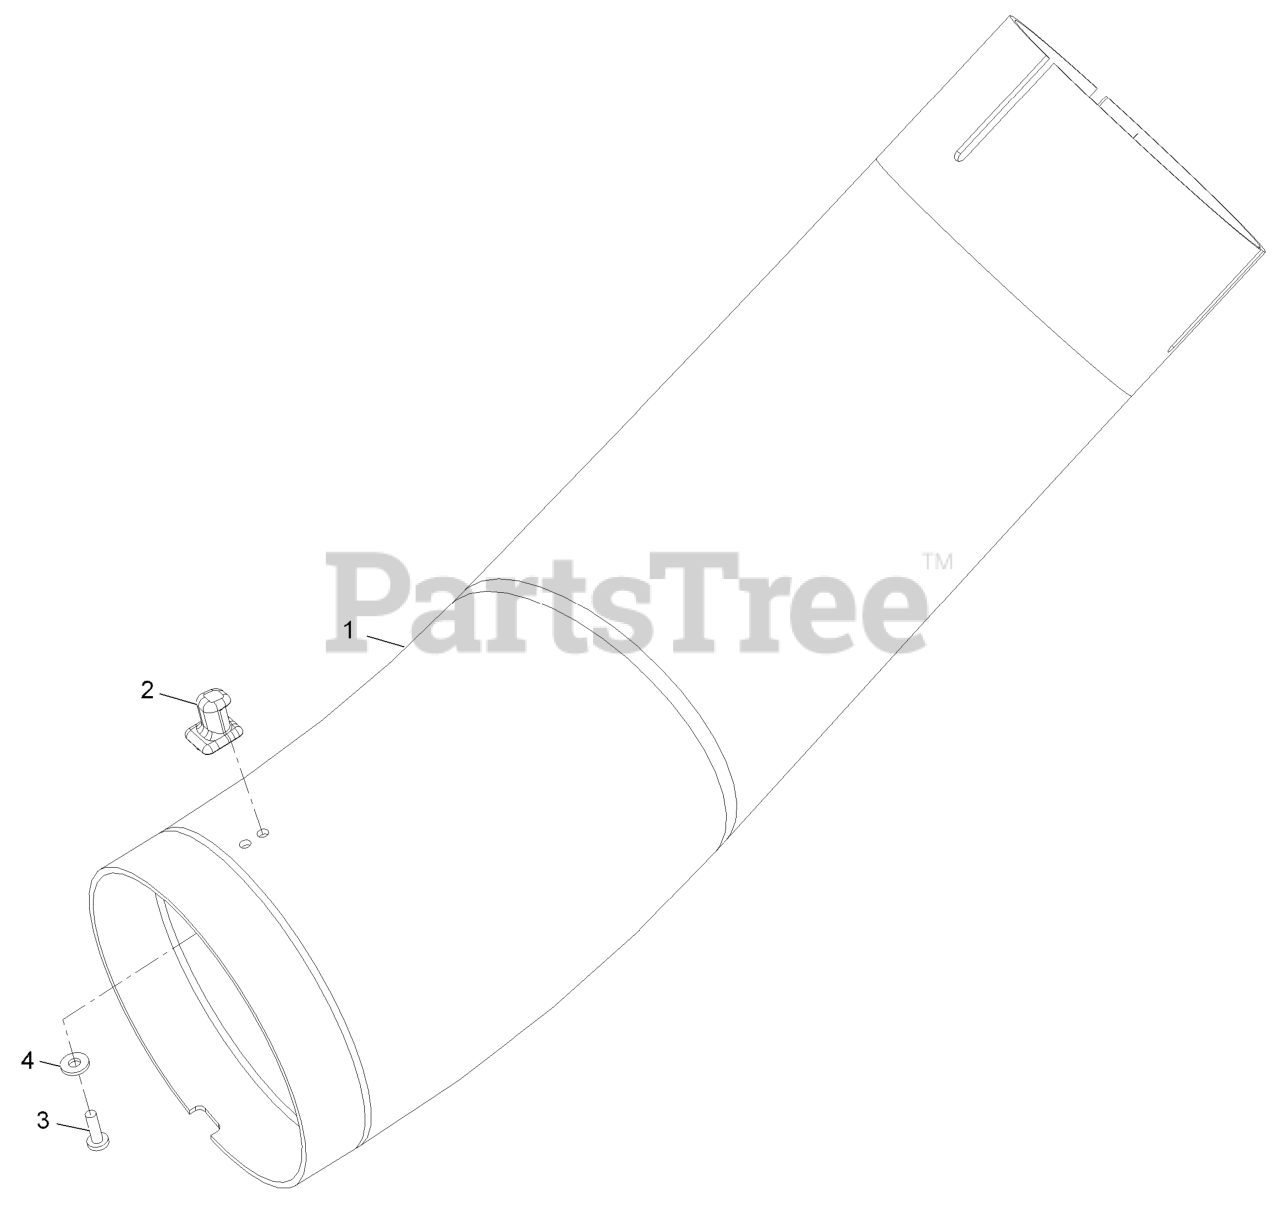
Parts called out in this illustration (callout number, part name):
1	Tube-Lower, Short
2	Latch-Keeper
3	Screw-PPH #10-24 X 5/8
4	Washer-#10 Std
